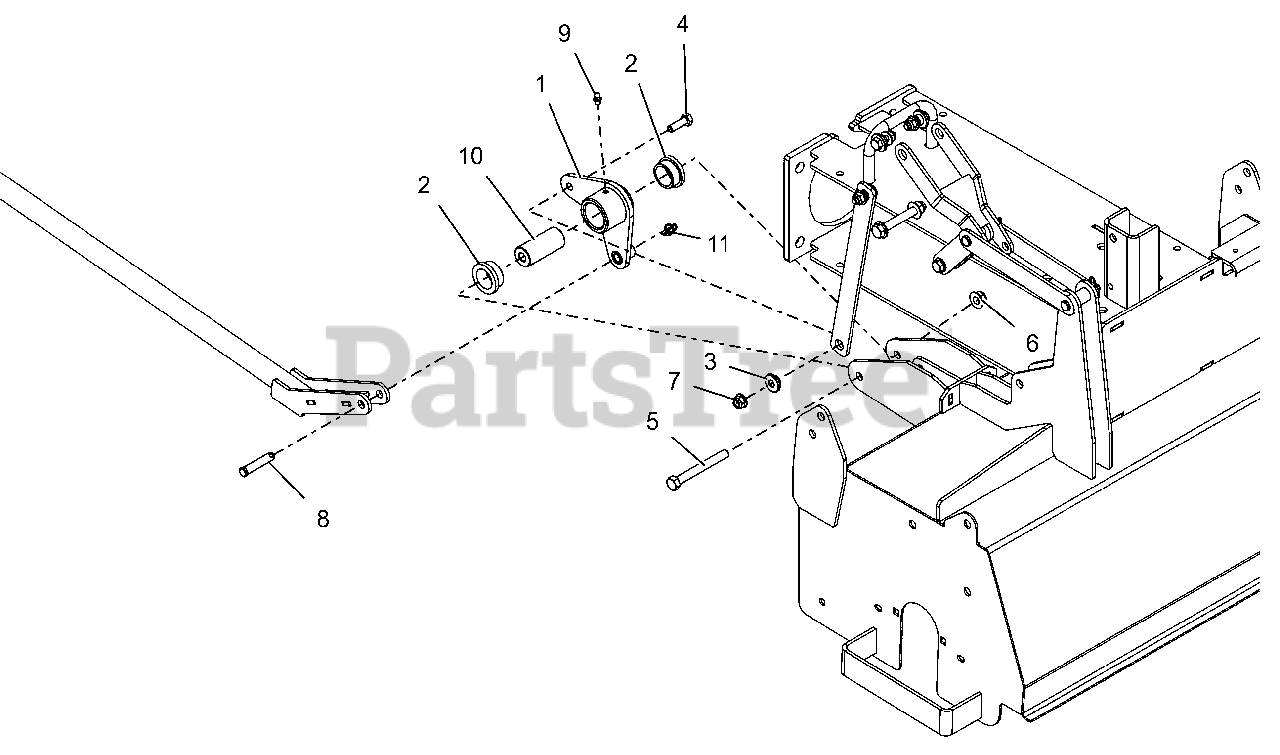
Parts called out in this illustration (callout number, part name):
1	WLDMT, LINKAGE PIVOT
2	BSHG,FLG 1.0 X 1.25 X 1.5 X .6
3	BSHG-FLG .32X.500X.344X.880
4	BLT,HEX .31-18X1.00 G5 ZCC
5	BLT, HEX .38-16X3.25 G5 ZCC
6	NUT,NYL-FLG .38-16 GF ZCC
7	NUT,NYL-FLG .31-18 GF ZCC
8	PIN-CLEV .370X1.75
9	FTG-LUBE .25-28X.256 SST
10	SPCR, PIVOT
11	RING, RUE .375 X .054 X 1.254
